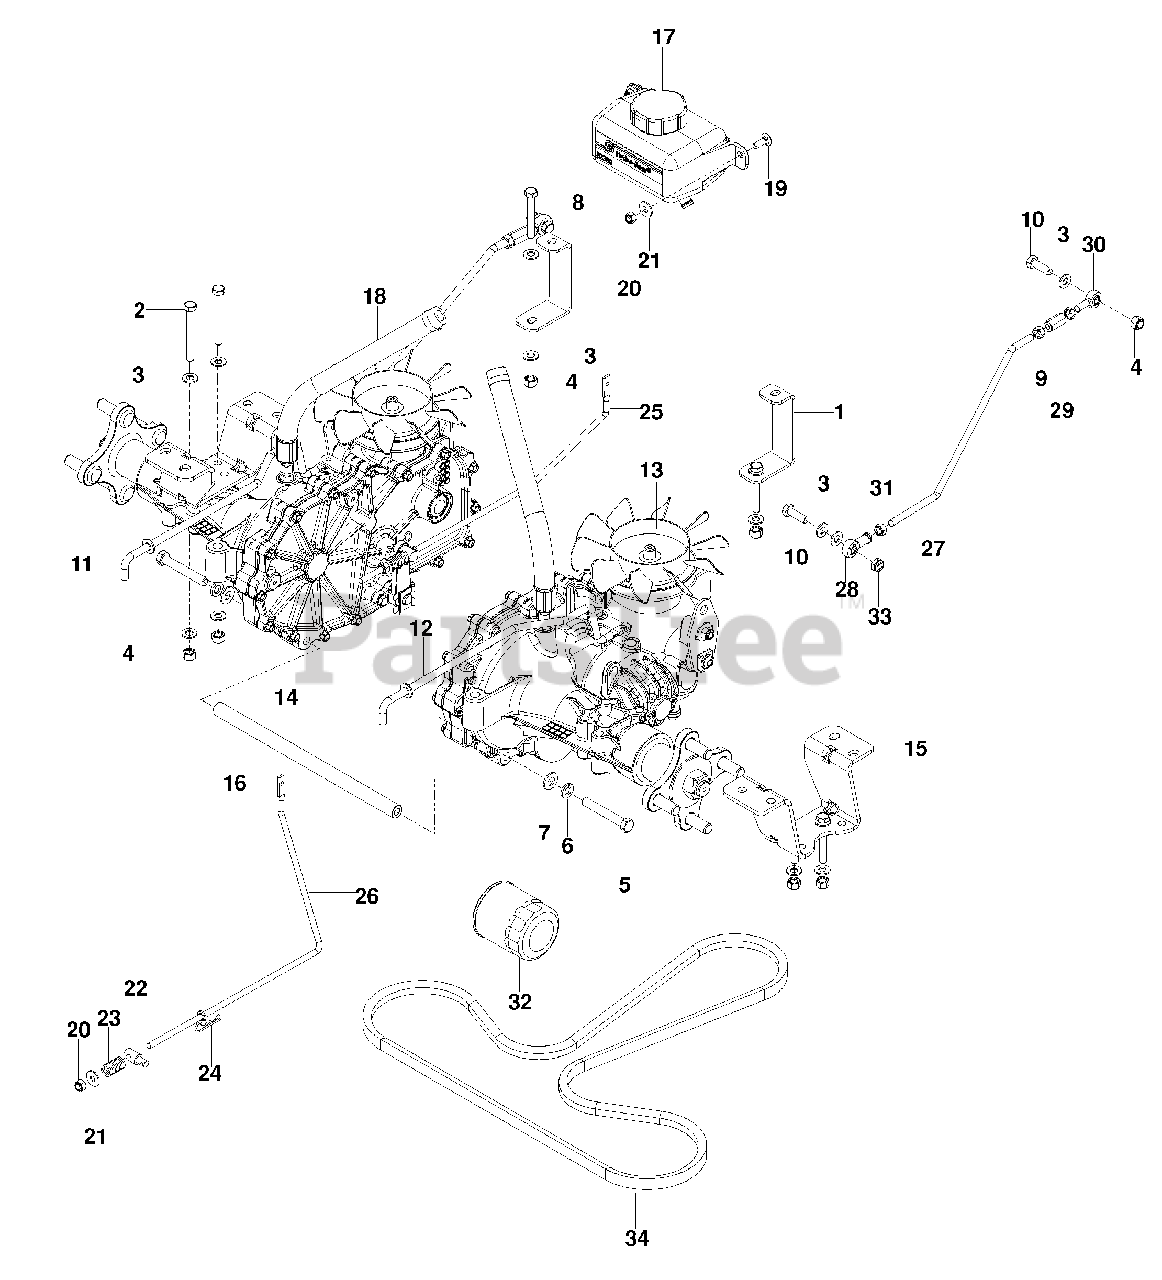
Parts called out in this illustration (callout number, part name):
1	SUPPORT, TRANSMISSION
2	HCS 5/16-18 x 2 3/4
3	WASHER 5/16 SAE FLAT
4	NUT 5/16-18 HEX NYLOC
5	HCS 3/8-16 x 2 1/2
6	WASHER, 3/8 SPLT LOCK
7	WASHER 3/8 SAE FLAT
8	HCS 5/16-18 x 2 1/4
9	NUT 5/16-24 HEX JAM LH
10	HCS 5/16-18 x 1
11	LINK ARM, BYPASS, RT
12	LINK ARM, BYPASS, LT
13	TRANS, ZT-2800 RT
14	TRANS, ZT-2800 LT
15	EZT MOUNT, REAR
16	SPACER TUBE, EZT
17	EXPANSION TANK w/CAP
19	RHSNB 1/4-20 x 3/4 GR2
20	NUT 1/4-20 HEX NYLOC
21	WASHER 1/4 FLAT
22	BRAKE SWIVEL
24	HAIRPIN COTTER
25	ROD, EZT BRAKE LT
26	ROD, EZT BRAKE RT
27	ROD, MOTION CONTROL
28	ROD END RH
29	COUPLER, ROD END
30	ROD END MALE LH
31	NUT 5/16-24 HEX
33	NUT 5/16-18 HEX NYL INSERT
34	BELT, HYDRO
